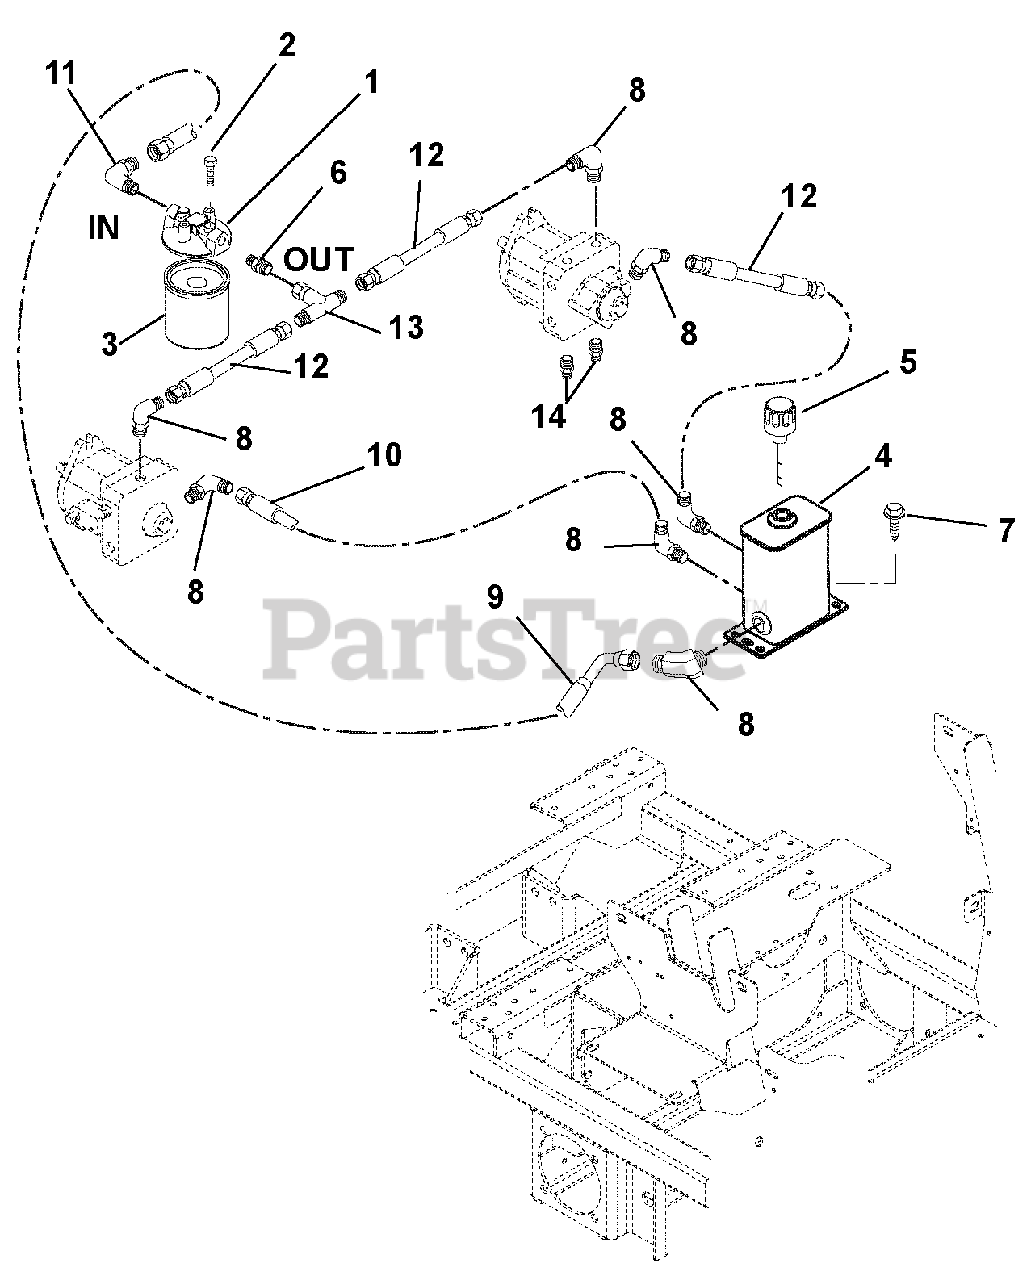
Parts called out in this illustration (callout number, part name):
1	Head, Filter
2	Bolt, Hex .25-20 x .50 Grade 5 Epoxy
3	Filter Element
4	Body, Hydraulic Tank
5	Breather, Dipstick
6	Fitting, Hydraulic, Straight
7	Screw, Tapping Hex Washer Head .38-16 x .75
8	Fitting, Hydraulic, 90° Elbow
9	Hose, Hydraulic Valve to Tank
10	Hose, Hydraulic, 10"
11	Fitting, Hydraulic, 90° Elbow
12	Hose, Hydraulic .50, 5"
13	Fitting, Hydraulic Tee
14	Fitting, Hydraulic (4 F5OLO)
